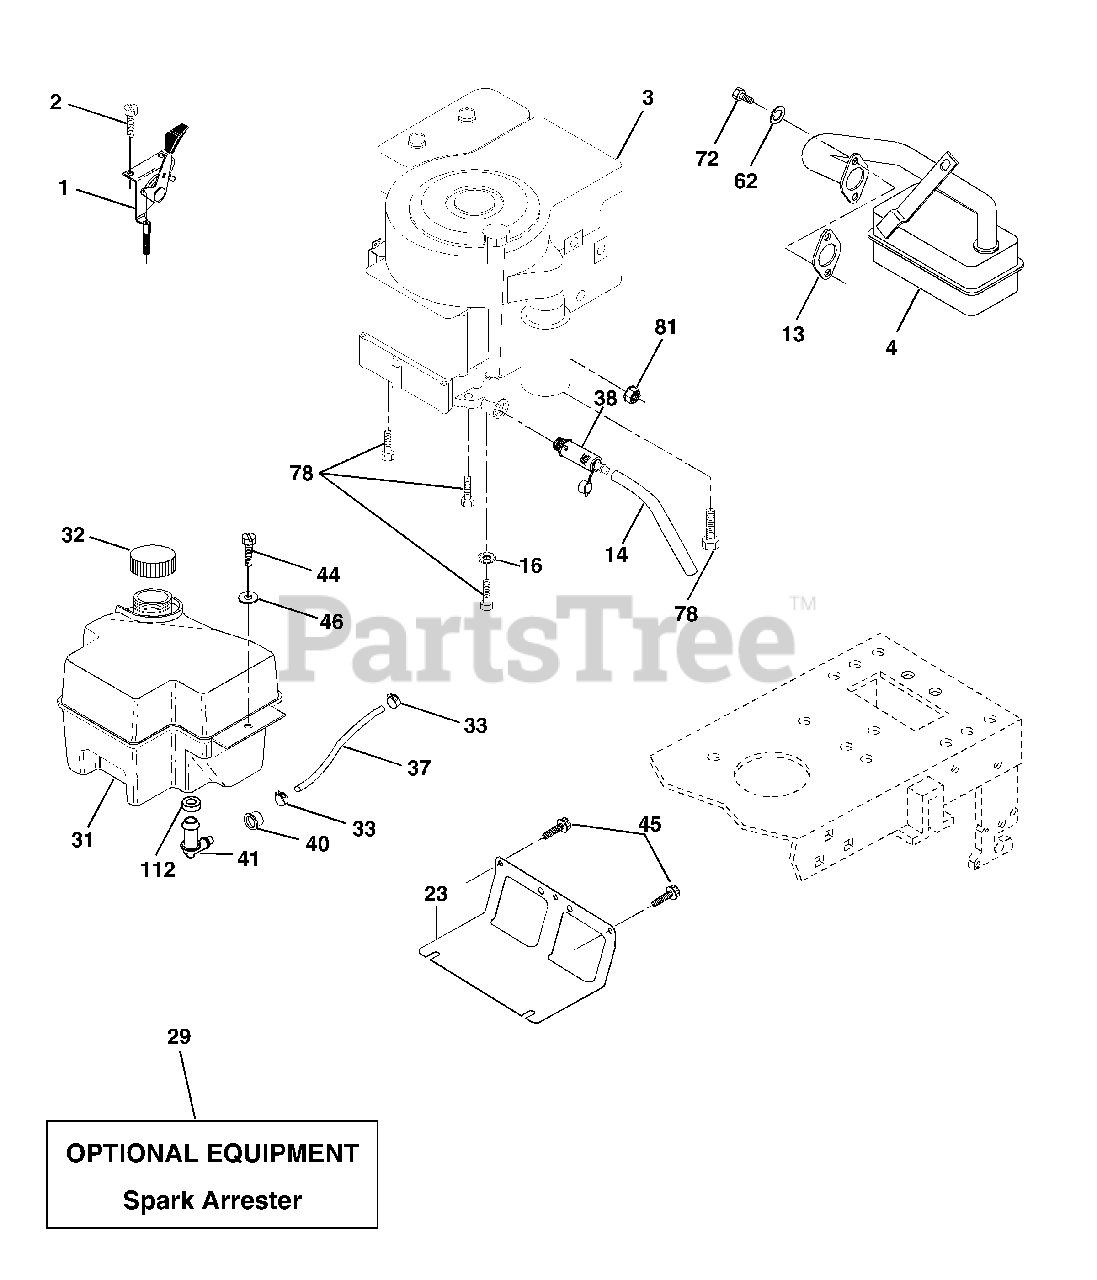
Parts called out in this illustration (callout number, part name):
1	Control Th/ch Flag
2	Screw Hex Thd Cut 1/4-20 x 1/2
4	Muffler
13	Gasket Eng
14	Tube Drain Oil Easy
16	Washer Lock Ext Tooth 3/8
23	Shield Brn/Dbr Guard
29	Kit Spark Arrestor (Flat Scrn)
31	Tank Fuel Front
32	Cap Asm Fuel W/sym Vented
33	Clamp Hose Black
37	Line Fuel 20"
38	Plug Drain Oil Easy
40	Bushing Snap Nyl Blk Fuel Line
41	Stem Tank Fuel
44	Screw Hexwsh Thdrol 1/4-20x3/4
45	Screw Hexwsh Thdr 3/8-16 x 3/4
46	Washer 9/32 X 7/8 X 16 Ga
62	Washer Lock Hvy Hlcl Spr 5/16
72	Screw Hex Hd Cap 5/16-18 x 3/4
78	Screw 3/8-16x1-1/4
81	Nut Keps Hex 1/4-20 UNC
112	Bushing
